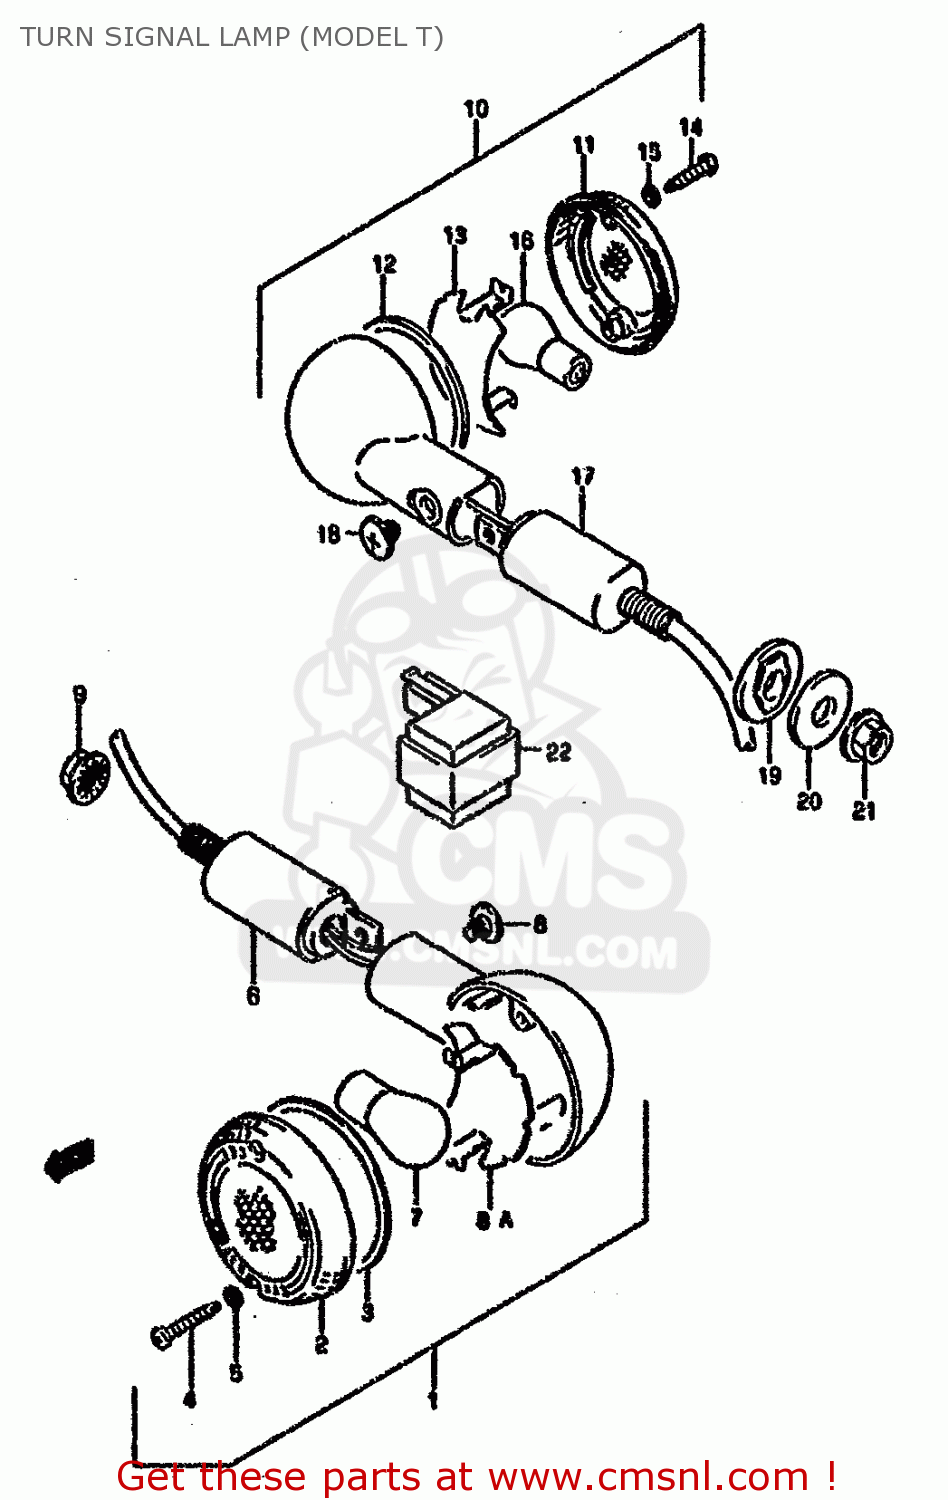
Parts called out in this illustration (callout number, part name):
1	LAMP ASSY,FR TURN SIGNAL
2	LENS
3	GASKET (NAS)
4	SCREW
5	GASKET (NAS)
6	STAY,TURNSIGNAL FR
7	BULB(12V21W)
8	SCREW
8A	REFLECTOR
9	NUT
10	LAMP ASSY,RR TURNSIGNAL,R
11	LENS
12	GASKET (NAS)
13	REFLECTOR
14	SCREW
15	GASKET (NAS)
16	BULB(12V21W)
17	STAY,TURNSIGNAL RR
18	SCREW
19	SPACER,RR TURNSIGNAL
20	WASHER(10.5X30X2.3)
21	NUT
22	RELAY ASSY,TURNSIGNAL
23	RELAY ASSY,TUR
